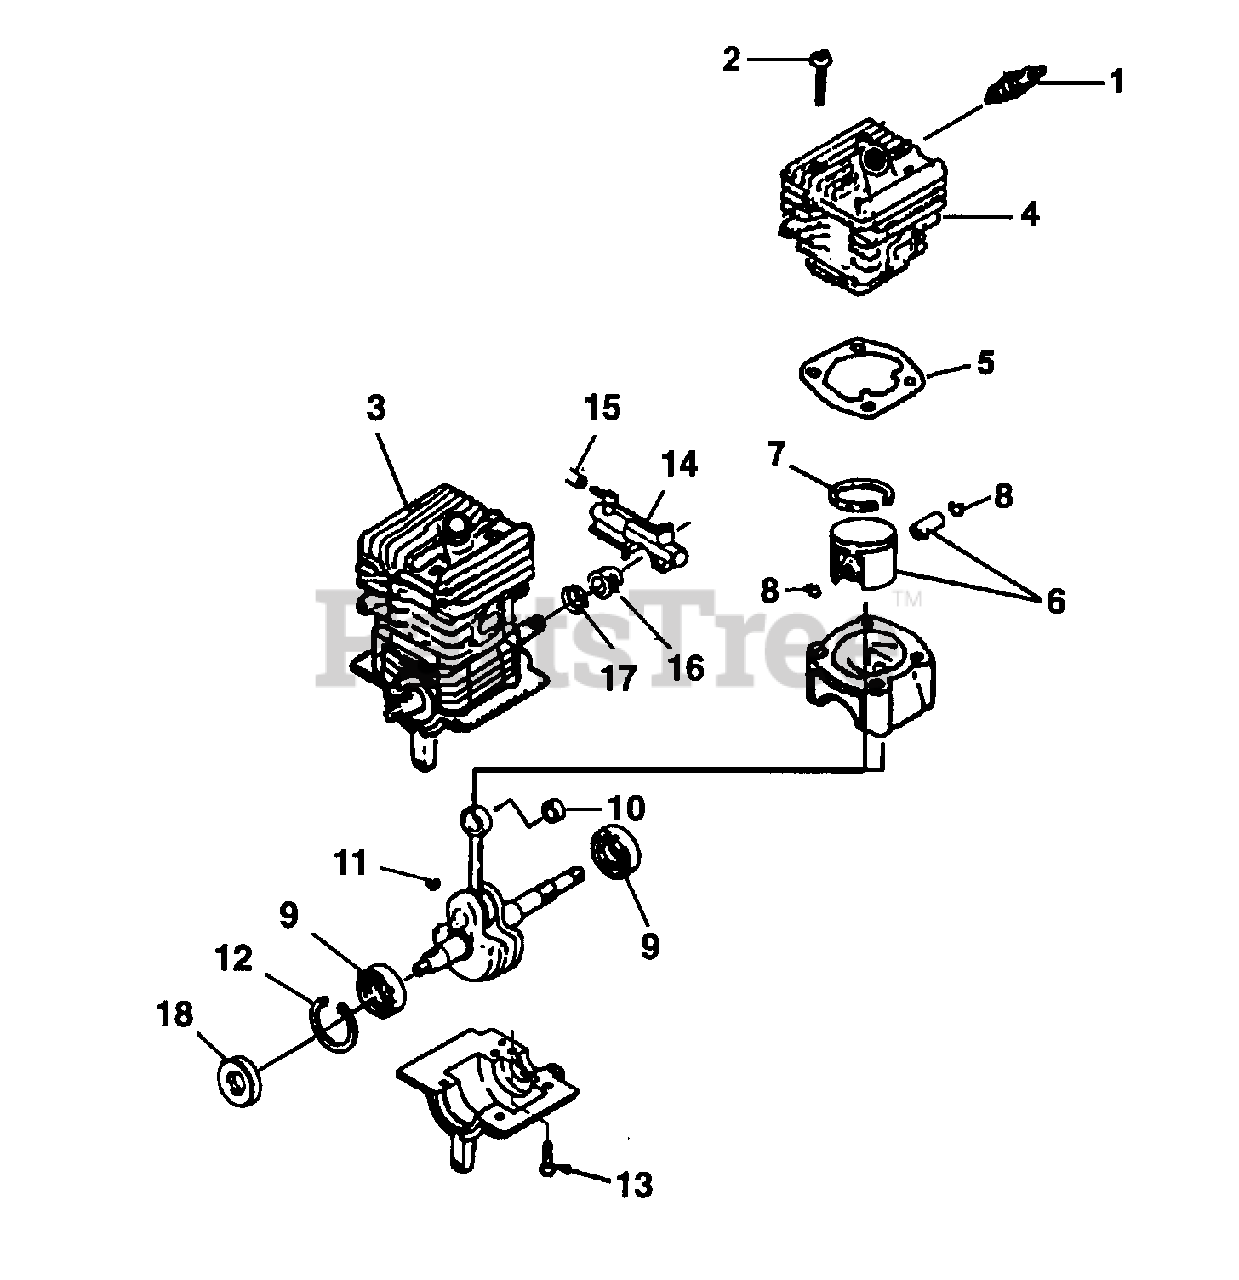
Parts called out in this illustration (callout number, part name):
1	SPARK PLUG (CJ6Y)
2	SCREW-PAN Hd. (10-24 x .800)
3	SHORT BLOCK
4	CYLINDER & GASKET
5	GASKET, CYLINDER
6	PISTON & PIN
7	RING, PISTON
8	RING, WRIST PIN, RETAINING
9	BEARING, BALL
10	BEARING, NEEDLE
11	WOODRUFF KEY
12	RETAINING RING
13	SCREW, FIL HD. (8-32 x 5/8")
14	OIL PUMP
15	TUBING, OIL
16	WORM GEAR, LEFT HAND
17	SEAL, CRANKSHAFT
18	SEAL, SHAFT
